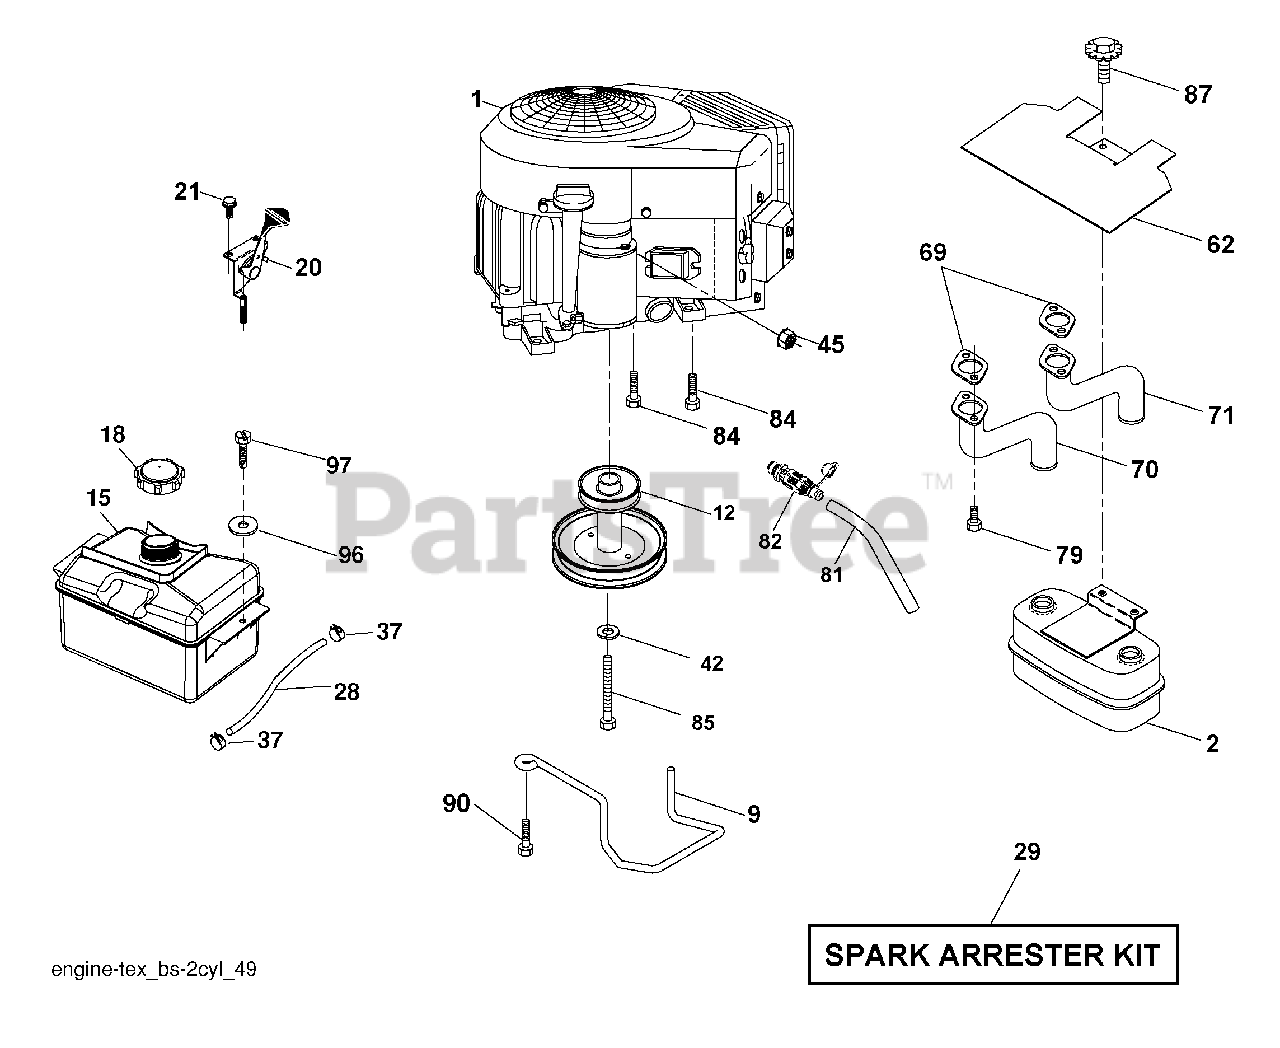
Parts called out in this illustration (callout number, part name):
9	Keeper Belt Engine
12	Pulley Engine
15	Tank Fuel
18	Cap Asm
20	Control Throttle/Choke
21	Screw #10 x 0.750 BOS Thread
28	Fuel Line
29	Spark Arrester Kit
37	Clamp Hose
42	Washer Lock 7/16
45	Nut Keps Hex 1/4-20 unc
62	Shield Heat
70	Exhaust Tube LH
71	Exhaust Tube RH
79	Screw 5/16-18 x 1
81	Tube Drain Oil Easy
82	Valve Drain Oil
84	Screw 3/8-16 x 1/4
85	Bolt Hex 7/16-20 x 4 Gr. 5
87	Bolt 5/16-18 unc x 3/4 w/sems
90	Screw 3/8-16 x 1
96	Washer 9/32 x 7/8 x 16 Ga.
97	Screw 1/4-20 x 3/4
